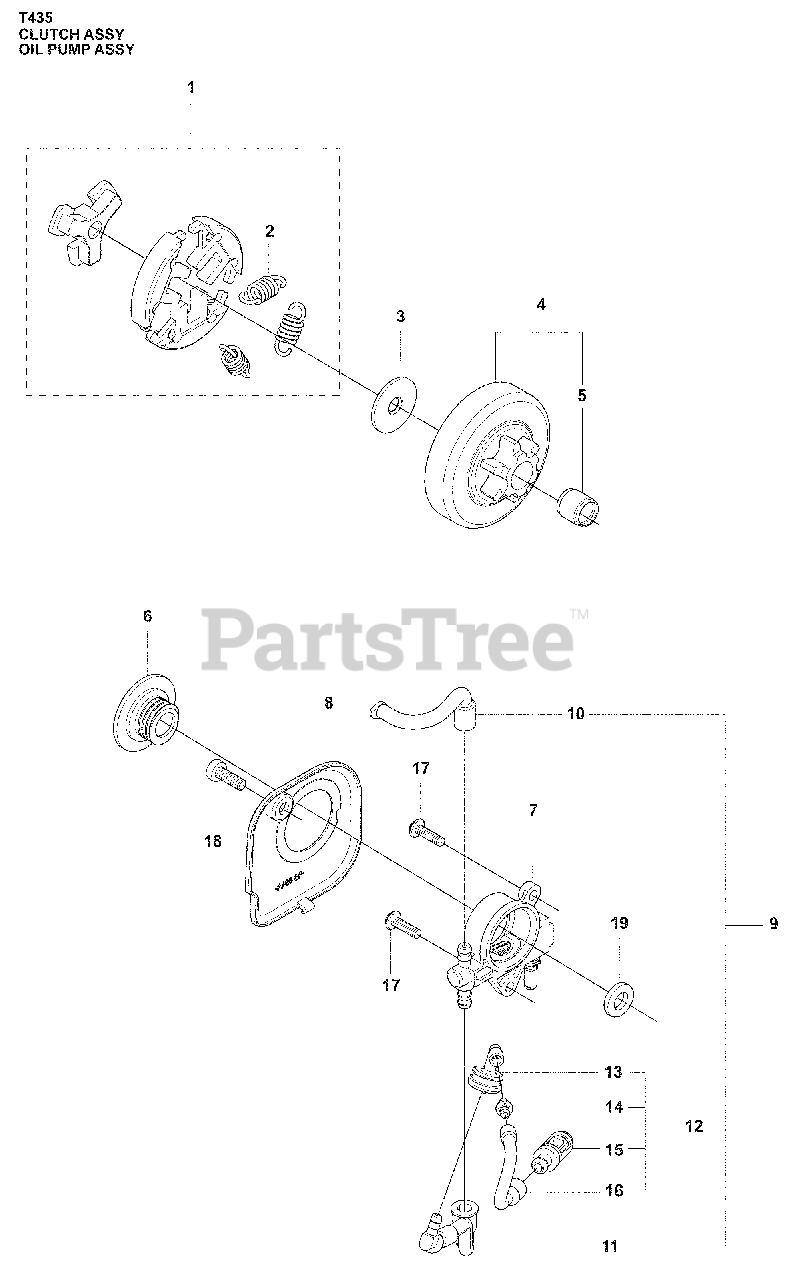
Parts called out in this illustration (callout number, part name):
1	Clutch assy
2	Clutch spring
3	Plate
4	Clutch drum 3/8 6T
5	Bearing
6	Worm wheel
7	Oil pump
8	Cover oil pump
9	Oil hose assy
12	Oil filter assy
13	Oil pipe
15	Filter
16	Oil hose
19	Washer
